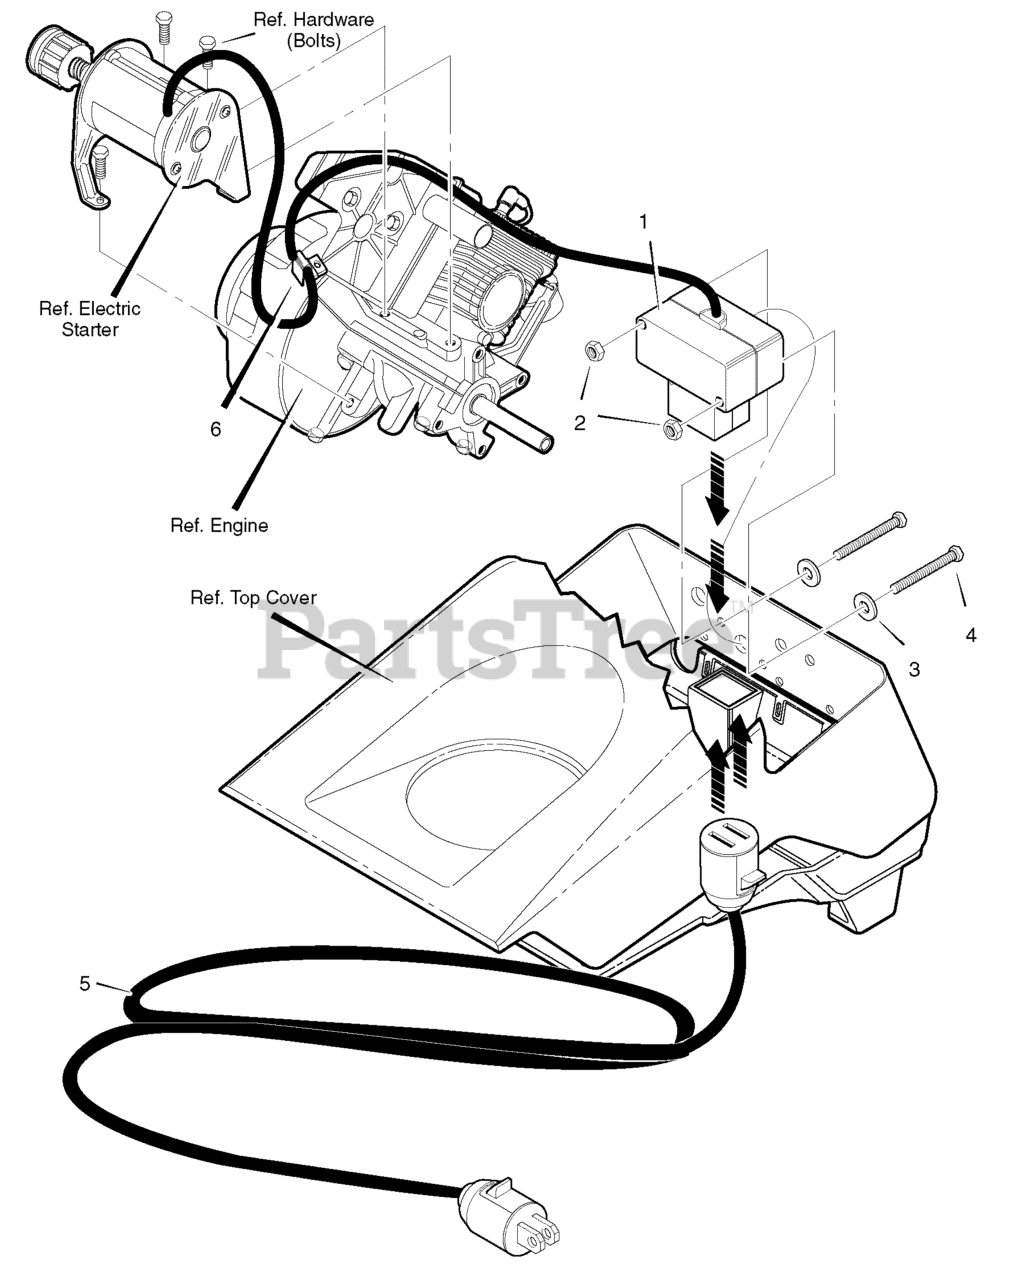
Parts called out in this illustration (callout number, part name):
1	INCLUDED WITH ENGINE
2	NUT, KEPS 8-32
3	WASHER, FLAT
4	SCREW 8-32x3.00
5	CORD, EXTENSION
6	STARTER CORD RETAINER
